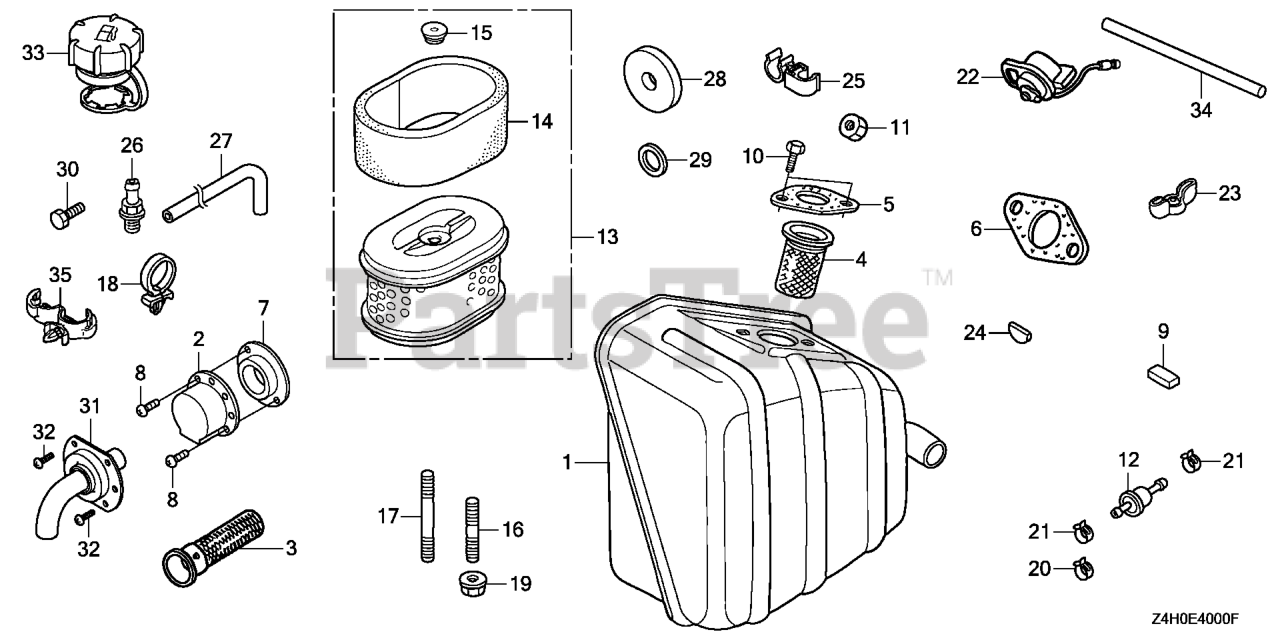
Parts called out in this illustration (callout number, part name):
2	DEFLECTOR
7	GUIDE, MUFFLER
8	SCREW, TAPPING (4X8)
9	KEY (4.78X4.78X38)
